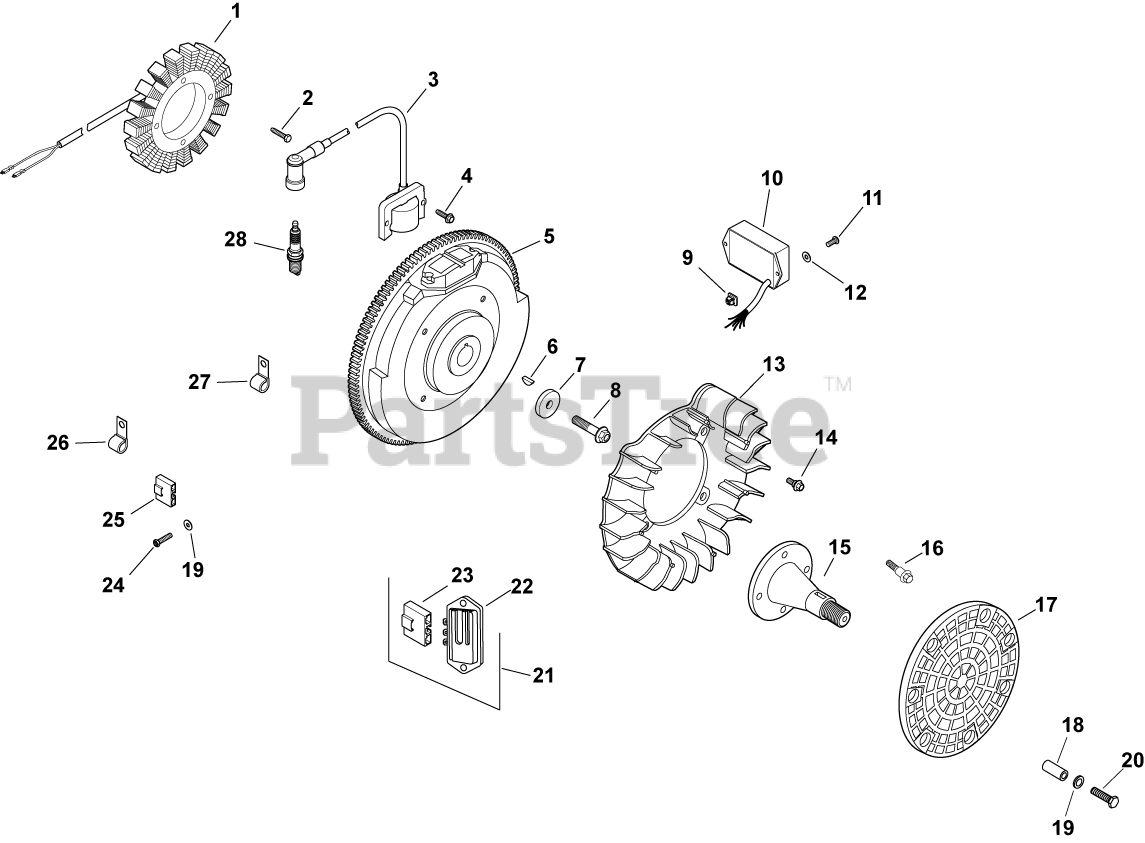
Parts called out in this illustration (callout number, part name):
1	KIT, 25 AMP STATOR ASSY.
2	SCREW, THD FROM M5X0.8X30
3	MODULE, IGNITION
4	SCREW, SKT THD FRM M5X0.8X25
5	FLYWHEEL, PAINTED-USE 24 025 57-S
6	KEY, 3/16" X 5/8"
7	WASHER, FLAT 13/32"
8	SCREW, FLG M10X1.5X45 - (#25086361S)
9	NUT, PLASTIC
10	MODULE, SPEED ADVANCE-DISCONTINUED SEE PB265
11	SCREW, PHL HD #11-16X1/2"
12	WASHER, FLAT 1/4" (O.D. 1/2")
13	FAN USE 24 157 11-S
14	BOLT, SHOULDER
15	SCREW, FLG M8X1.25X25
16	KIT, FRONT DRIVE SHAFT
17	SCREEN, GRASS-USE 24 162 45-S
18	SPACER - DISCONTINUED
19	WASHER, FLAT 3/16"
20	SCREW, SLT HD CAP M4X0.7X25
21	KIT, FULL WAVE CONVERSION
22	REG/RECTIFIER (20/25 AMP)-USE 25 403 20-
23	CONNECTOR, BODY (KM)-USE 25 155 41-S
24	SCREW, PHL HD #11-16X7/8"
25	CONNECTOR
26	CLIP, CABLE
28	PLUG, SPARK (STD)
